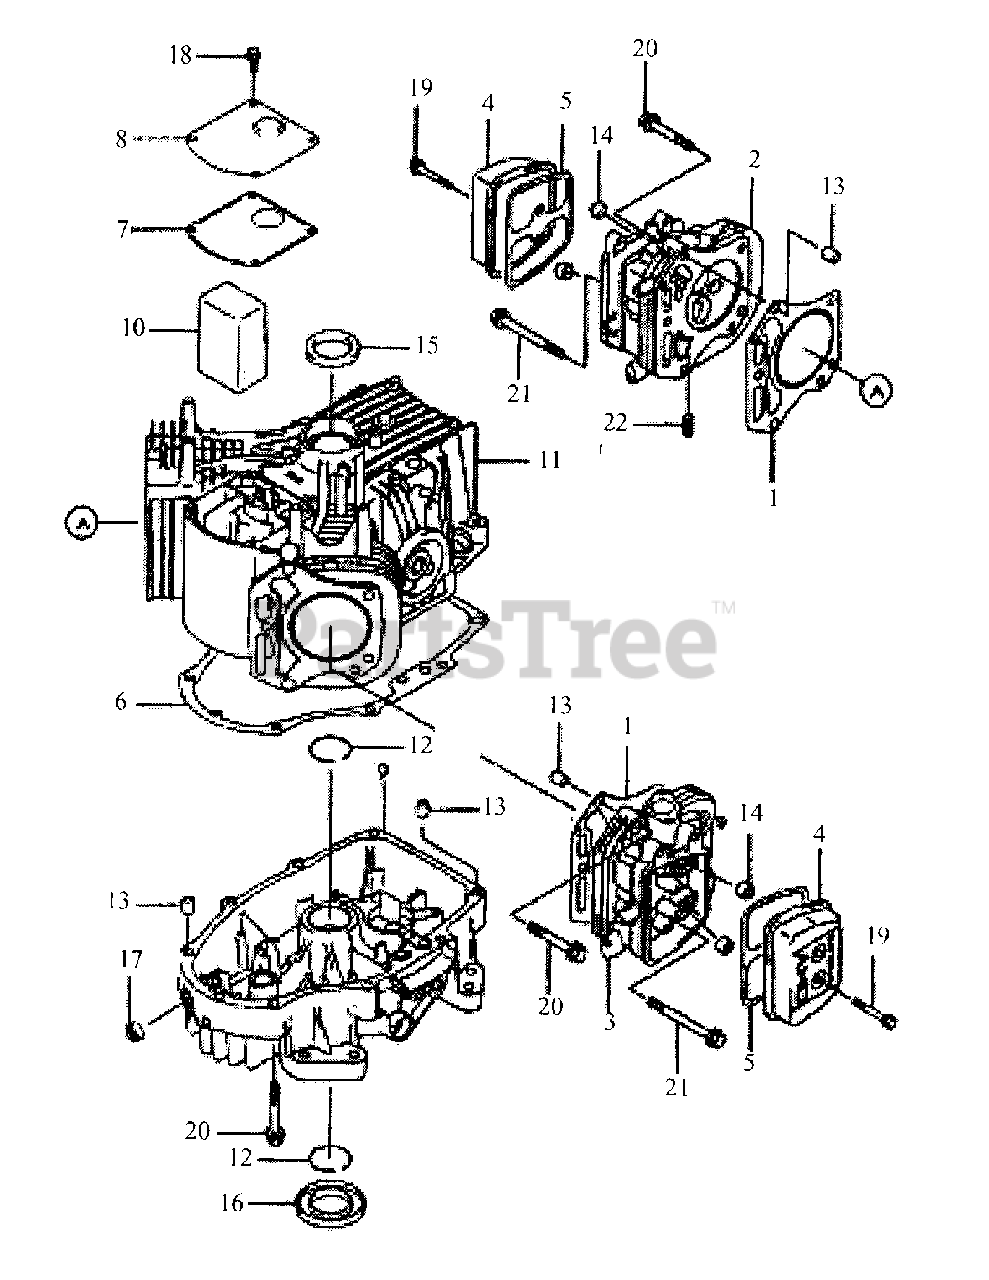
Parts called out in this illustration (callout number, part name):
1	Head Gasket
2	Head, Cylinder #1
3	Head, Cylinder #2
4	Case, Rocker
5	Gasket, Rocker Case
6	Gasket, Crankcase
7	Gasket, Breather
8	Cover, Breather
10	Element, Breather
11	Crankcase, Complete
12	Ring, Snap
14	Seal, Oil
15	Seal, Oil
16	Seal, Oil
17	Seal, Oil
18	Bolt, Flange
19	Bolt, Flange
20	Bolt, Flange
21	Bolt, Flange
22	Bolt, Stuc
